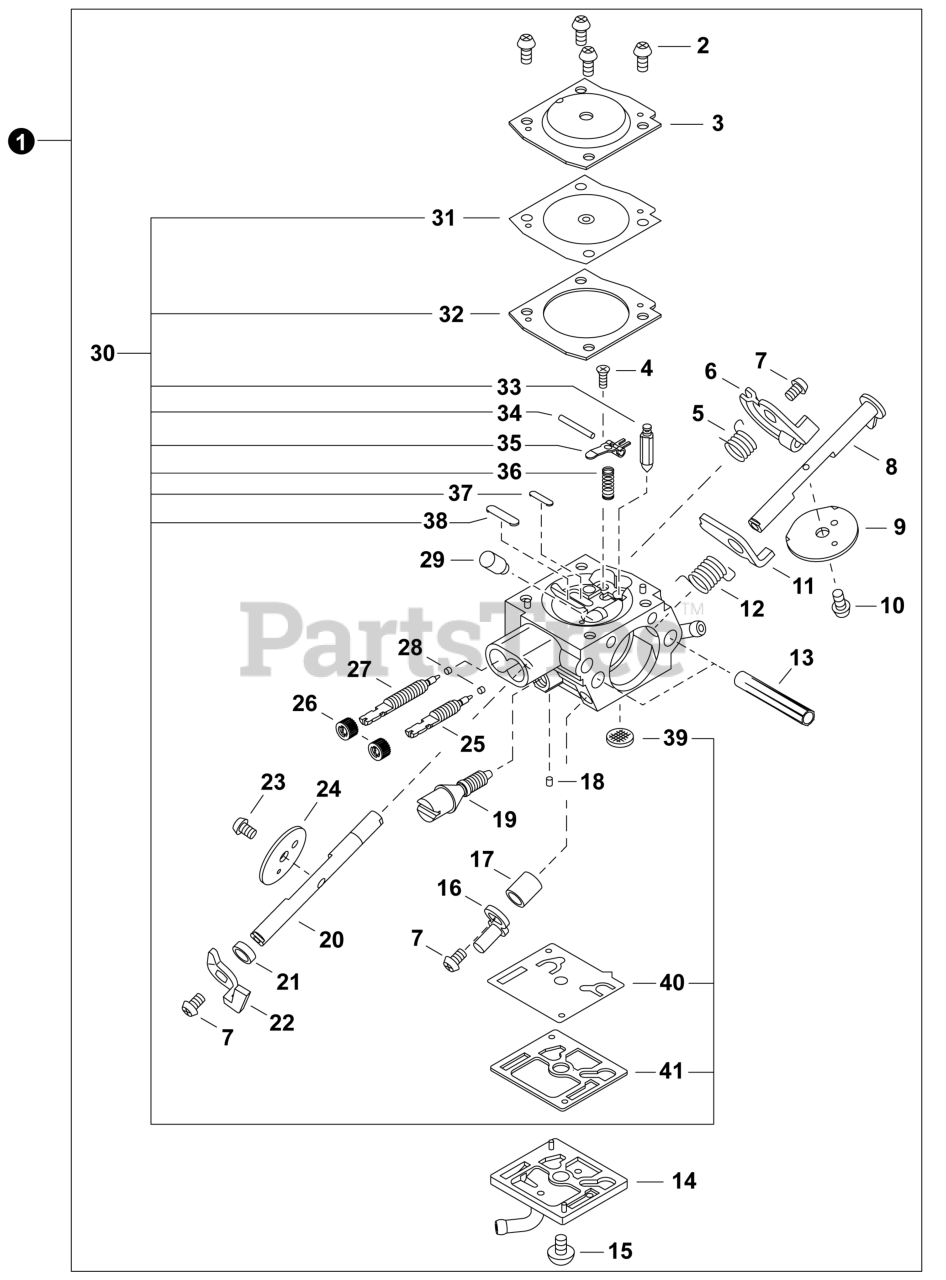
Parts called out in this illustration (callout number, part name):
1	CARBURETOR YZ0009
3	COVER, METERING DIAPHRAGM
5	SPRING, THROTTLE
6	LEVER, THROTTLE
8	SHAFT, CHOKE
9	VALVE, CHOKE
10	SCREW 3x4.5
11	LEVER, CHOKE
12	SPRING, CHOKE RETURN
13	COLLAR 4
14	COVER, FUEL PUMP
16	LEVER, CHOKE
18	PIECE, FRICTION
19	SCREW, IDLE ADJUST
20	SHAFT, THROTTLE
22	LEVER, THROTTLE
24	VALVE, THROTTLE
25	NEEDLE, HIGH SPEED
26	CAP, LIMITER
27	NEEDLE, LOW SPEED
28	RETAINER
29	NOZZLE ASSY
30	REPAIR KIT, CARBURETOR
31	DIAPHRAGM, METERING
32	GASKET, METERING DIAPHRAGM
33	VALVE, INLET NEEDLE
34	PIN, METERING LEVER
35	LEVER, METERING
36	SPRING, METERING LEVER
37	PLUG, WELCH
38	PLUG, WELCH
39	SCREEN, FUEL INLET
40	DIAPHRAGM, FUEL PUMP
41	GASKET, FUEL PUMP
